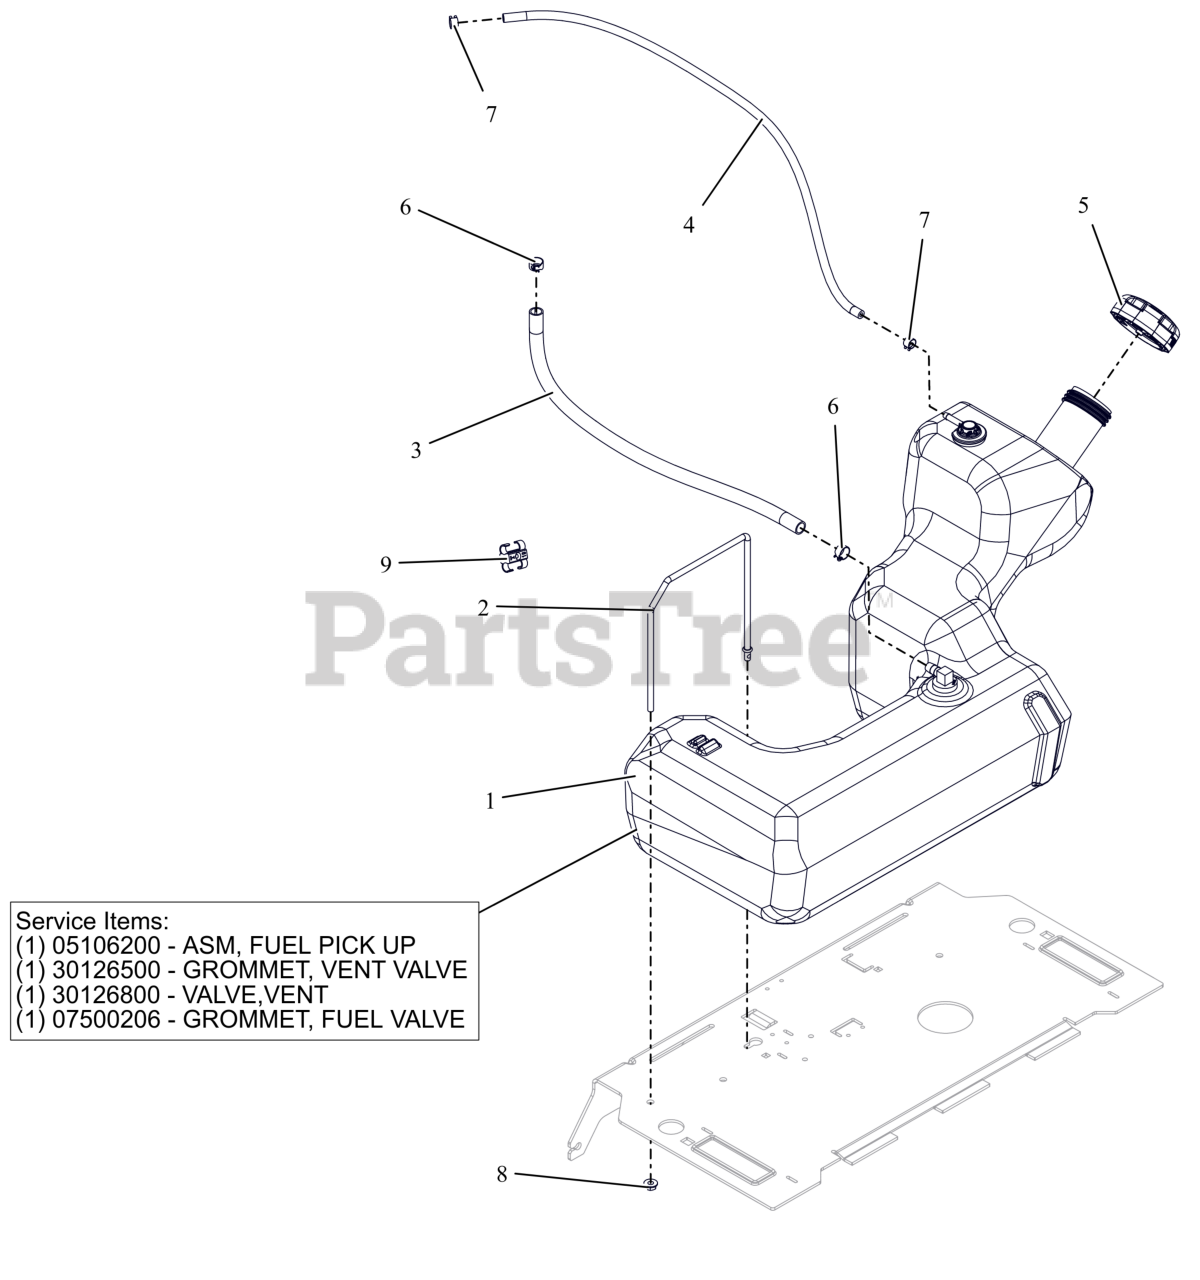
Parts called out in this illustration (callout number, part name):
1	ASM, FUEL TANK - IKON 23
1	ASM, IKON FUEL PICK-UP
1	GROMMET, VENT VALVE
1	VALVE, VENT
1	BSHG-FLG .375X1.062X.625 NITR
2	STRAP, TANK HOLD DOWN
3	1 INCH OF HOSE, .25 LOW-PERM BULK GAS
4	HOSE, .188 30R7 BULK
5	CAP-FUEL- 2.25 RATCHET INLET V
6	CLAMP, FUEL LINE
7	CLAMP-HOSE, SPRING .188
8	NUT-LK-CTR-FLG .25-20 ZC120
9	CLIP, T, .38-.50
